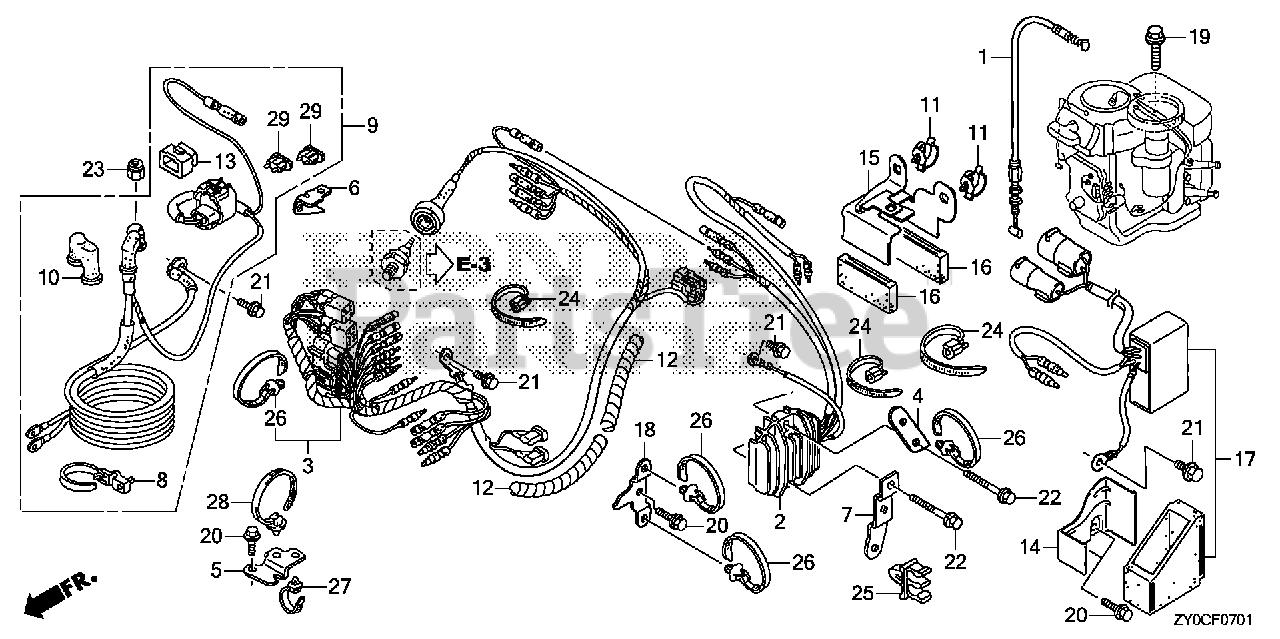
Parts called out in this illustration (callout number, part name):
1	CABLE, NEUTRAL STARTING
2	RECTIFIER ASSY., REGULATOR
3	WIRE HARNESS ASSY. (REMOTE CONTROL)(PT)
4	BRACKET, CLIP F
5	BRACKET, STARTER CABLE
6	BRACKET, FUSE CASE (PT)
7	BRACKET, E-CLIP
8	BAND, WIRE
9	CABLE ASSY., STARTER (PT)
10	COVER, MAGNETIC SWITCH TERMINAL
11	CLAMP, WIRE
12	TUBE, SPIRAL A
13	COVER ASSY., FUSE (20A)
14	BRACKET, RELAY (PT)
15	BRACKET, CONNECTOR A
16	GROMMET, CONNECTOR
17	RELAY ASSY., POWER TILT
18	BRACKET, HARNESS CLIP
19	BOLT, FLANGE (6X20)
20	BOLT, FLANGE (6X14) (CT200)
21	BOLT, FLANGE (6X12)
22	BOLT, FLANGE (6X26) (CT200)
23	NUT, LOCK (6MM)
24	TIE, CABLE
25	CLIP, FUEL TUBE
26	CLIP, HARNESS BAND (151.5MM) (NATURAL)
27	BAND, WIRE HARNESS (123.5MM) (BLUE)
28	BAND, WIRE HARNESS (93.5MM) (WHITE)
29	FUSE, BLADE (20A)
